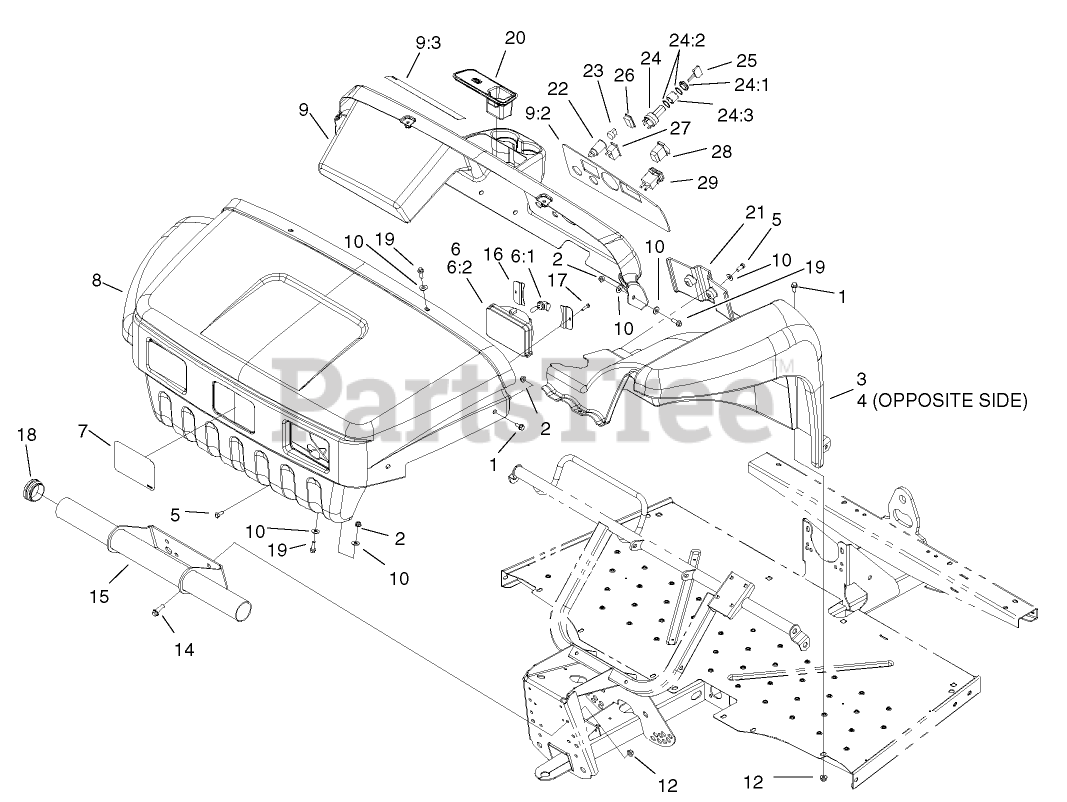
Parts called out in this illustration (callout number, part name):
1	SCREW-HHF
2	NUT-HF, NI
3	LH FENDER ASM
4	RH FENDER ASM
5	SCREW-HWH
6	HEADLIGHT
6:1	LAMP-12 VOLT
7	DECAL
9:2	DECAL-WARNING, DASH
10	WASHER-FLAT
12	NUT-HF, NI
15	BUMPER-TUBE
16	BRACKET-HEADLIGHT
17	SCREW-HWH
18	CAP-END
19	SCREW-HHF
20	PLUG-RUBBER
21	COVER-CHANNEL
22	POINT-POWER
24	SWITCH-IGNITION
24:1	NUT-SWITCH, PLASTIC
24:2	WASHER-LOCK, INTERNAL
24:3	SPACER-SWITCH
25	KEY-IGNITION
26	PLUG-HOLE
27	INDICATOR-LIGHT, LOW-OIL PRESSURE
28	SWITCH
29	HOURMETER
